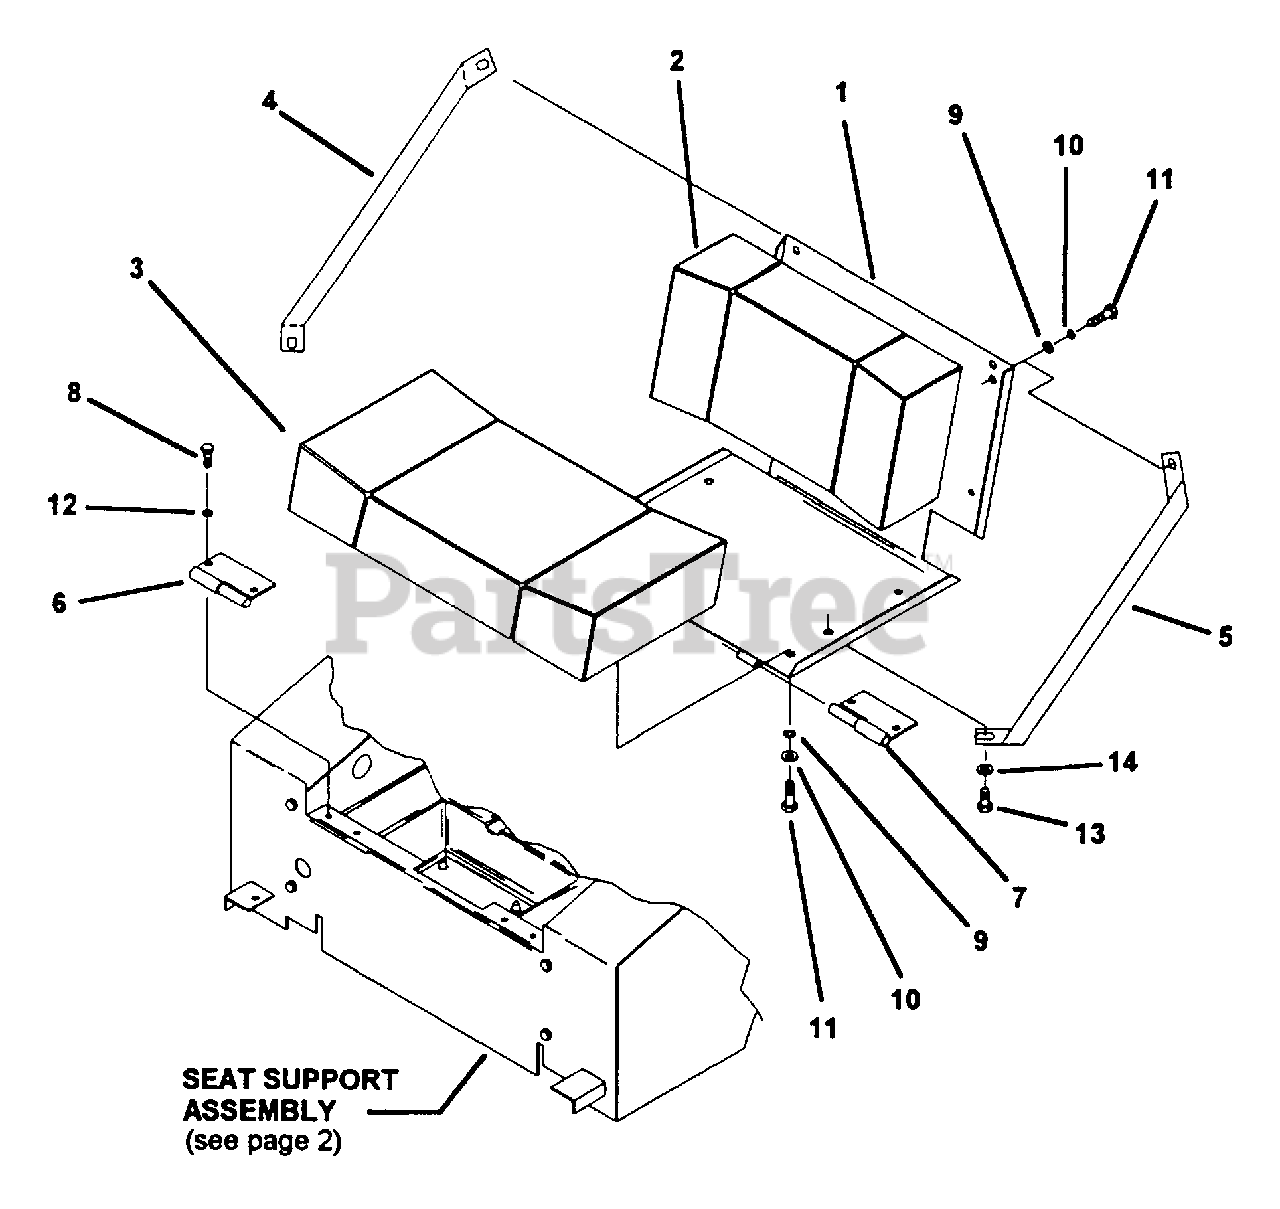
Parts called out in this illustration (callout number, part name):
1	SEAT BRACKET WLDT.
2	CUSHION BACK ASSEMBLY
3	CUSHION SEAT ASSEMBLY
4	GUSSET, SEAT RIGHT
5	GUSSET, SEAT LEFT
6	HINGE
8	BOLT, 1/4-20 X 3/4" GR. 5
9	WASHER, FLAT STD. 5/16"
10	LOCKWASHER, 5/16" SPLIT SPRING
11	BOLT, 5/16-18 X 1" GR. 5
12	LOCKWASHER, 1/4" SPLIT SPRING
13	BOLT, 5/16-18 X 5/8" LONG LOCK
14	WASHER, 5/16 ID X 5/8 OD X .035 THK
